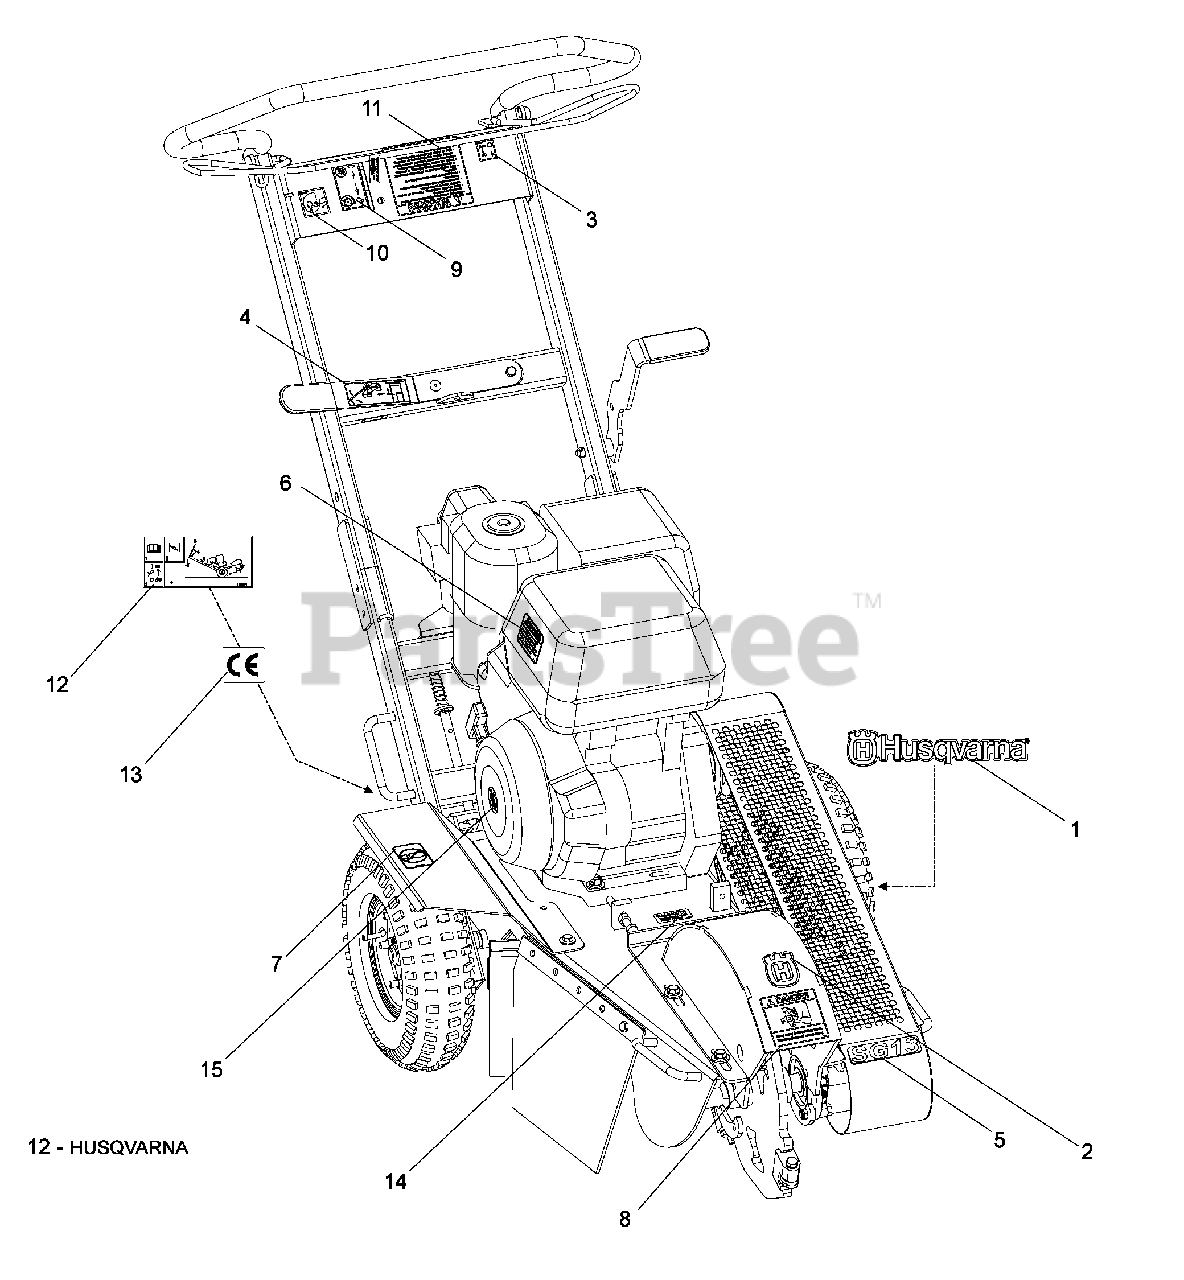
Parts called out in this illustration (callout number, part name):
1	DECAL, LOGO
2	DECAL, CROWN
3	DECAL, ON/OFF
4	DECAL, HANDLE ADJ
5	DECAL, SG13
6	DECAL, PROP 65
7	DECAL, NO STEP
8	DECAL, DANGER FOOT
9	DECAL, THROTTLE
10	DECAL, EAR/EYE WARN
11	DECAL, CAUTION LIST
12	DECAL, OPERATION
14	DECAL, CE966042701
15	DECAL, STARTER-HONDA
